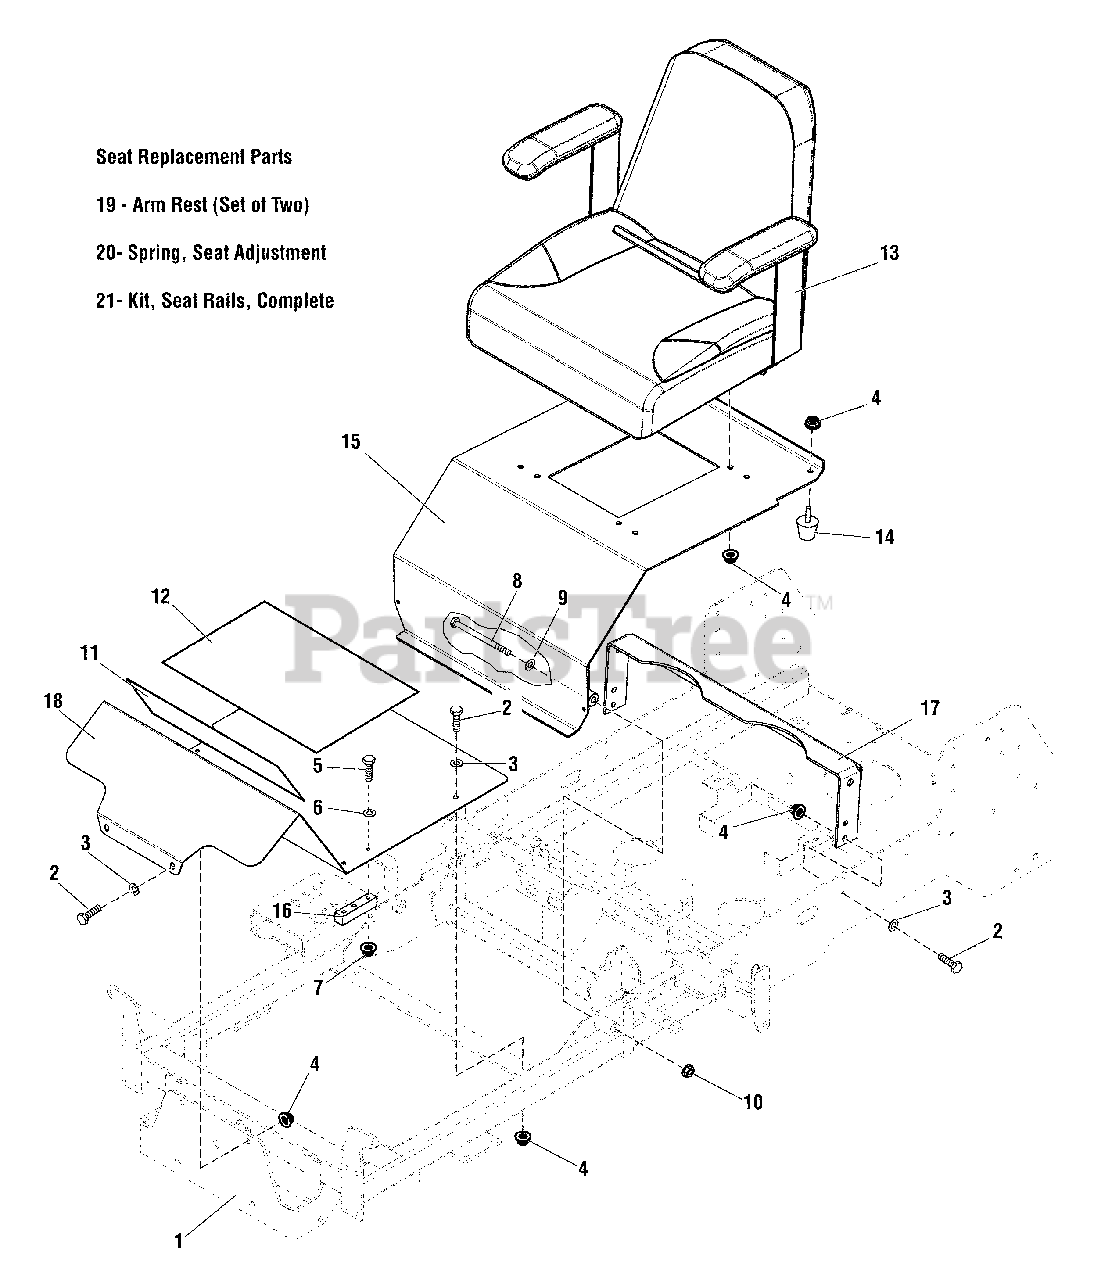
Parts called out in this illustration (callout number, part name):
1	MAIN FRAME
2	BOLT, 5/16-18 X 1 GD5 YZ
3	WASHER, 5/16" SAE
4	NUT, 5/16-18 HEX NYLOCK FLANGE
5	BOLT, 1/4-20 X 1-1/4, GD5
6	WASHER, 1/4 SAE (5025154)
7	NUT, 1/4-20 HEX NYLOCK FLANGE (5025391)
8	BOLT, 3/8-16 X 5-1/2 GD5 YZ
9	WASHER, 3/8 SAE
10	NUT, 3/8-16 HEX NYLOCK FLANGE
11	SAFETY WALK, 8.00 X 15.00
12	SAFETY WALK, 11.50 X 15.00
13	SEAT, XB-180, NO LOGO, BLACK
14	BUMPER, RUBBER 5/16-18
15	WELD, SEAT PLATE - IS2000 - ORG
16	BLOCK, DECK LIFT SUPPORT
17	WELD, SEAT SUPPORT - ORG
18	PLATE, FLOOR - ORG
19	ARM REST (SET OF 2)
20	SPRING, EXTENSION, SEAT ADJUSTMENT (BLK OR SLVR)
21	KIT, SEAT RAILS, COMPLETE
